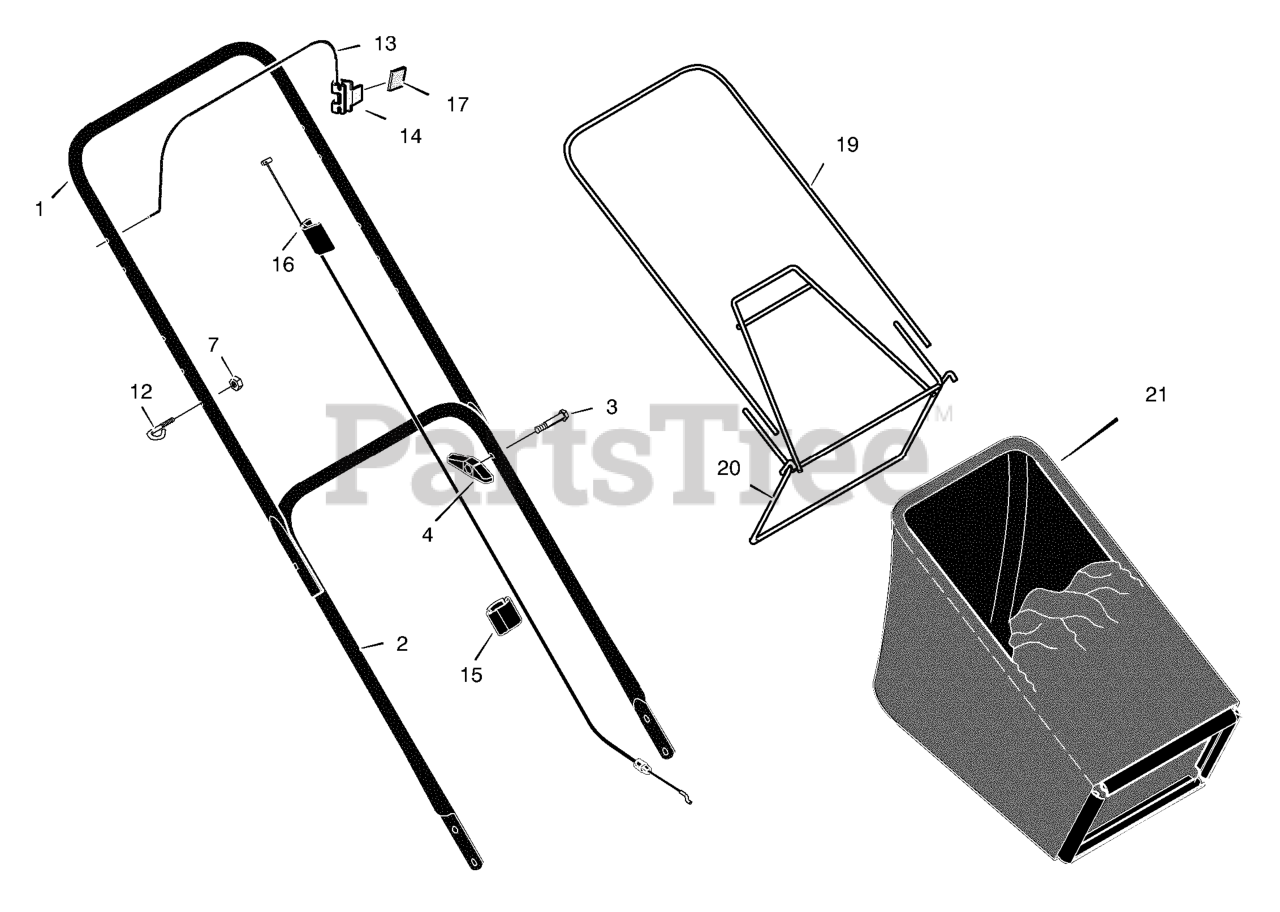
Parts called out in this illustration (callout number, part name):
1	Handle, Upper (Black)
2	Handle, Lower (Black)
4	Knob, Plastic
7	Locknut
12	Guide, Rope
13	Engine Stop Lever
14	Bracket, Stop Lever
15	Fastener, Cable
16	Engine Stop Cable
19	Frame, Top
20	Frame Assembly
21	Bag, Cloth - Black
